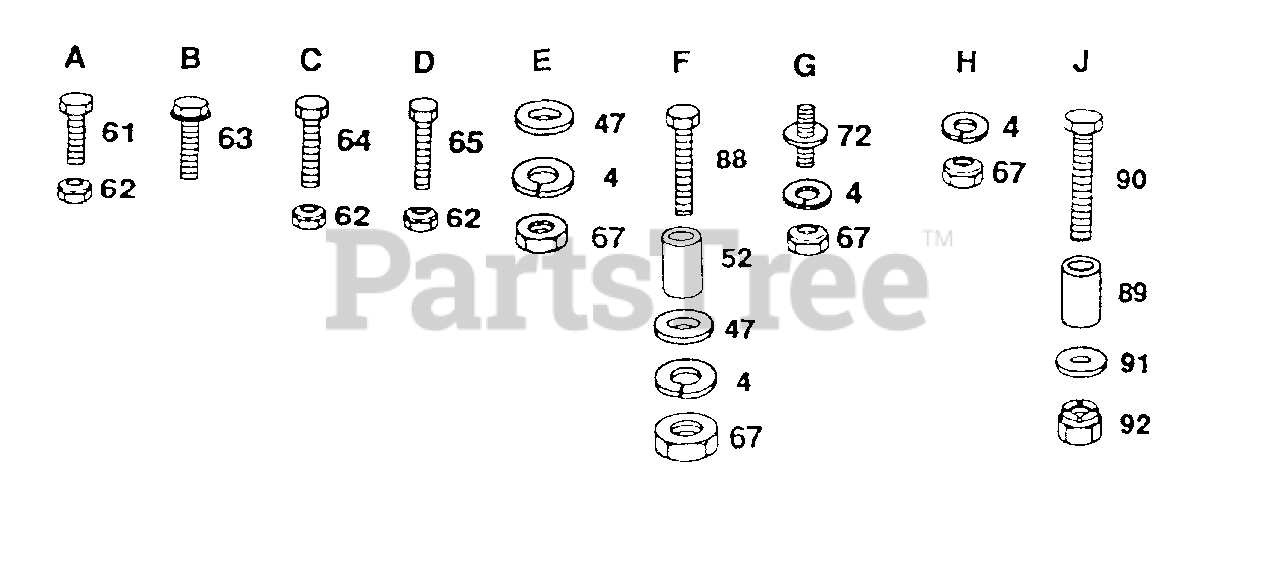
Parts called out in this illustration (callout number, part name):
4	Washer - Lock 3/8
47	Washer 13/32 x 7/8 x 13 Ga.
52	Spacer, Split
61	Bolt Hex 3/8 -16 x 3/4
62	Nut- Lock 3/8-16
63	Screw- Hex Wsh.Thdrol. 3/8 -16 x 3/4
64	Bolt-Hex 3/8 -16 x 1 Gr. 5
65	Bolt-Hex 3/8 -16 x 1
67	Nut-Hex 3/8 -16
72	Pin Mounting, Idler Bracket
88	Bolt-Hex 3/8-16 x 2 - 1/4
89	Bushing, Handle
90	Bolt-Hex 5/16-18 x 1
91	Washer 11/32 x 7/8 x 16 Ga.
92	Nut-Lock 5/16 -18
